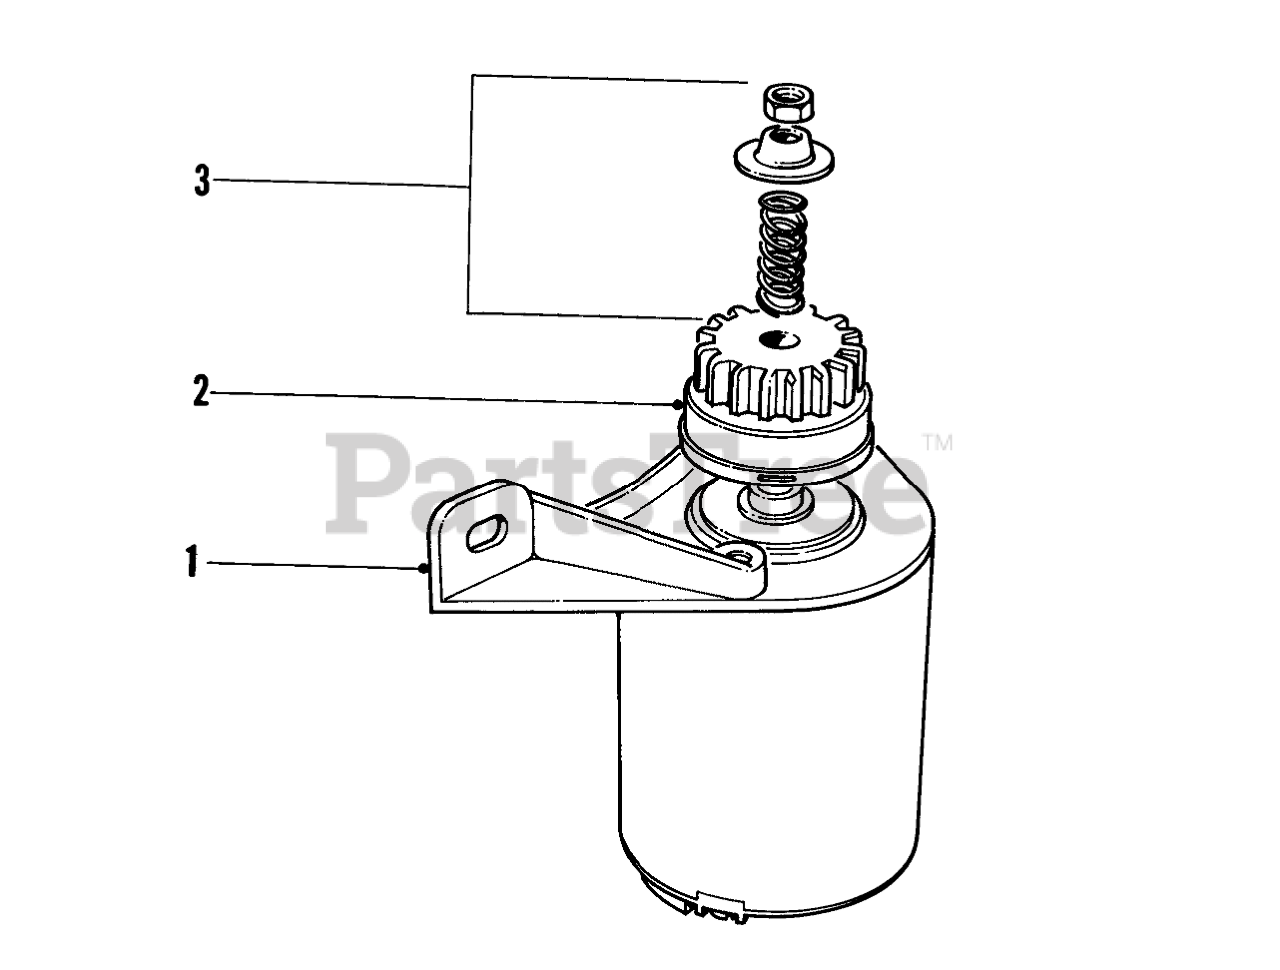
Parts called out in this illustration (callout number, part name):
1	Starter Motor
2	PINION ASM
3	Cup, Spring Kit
